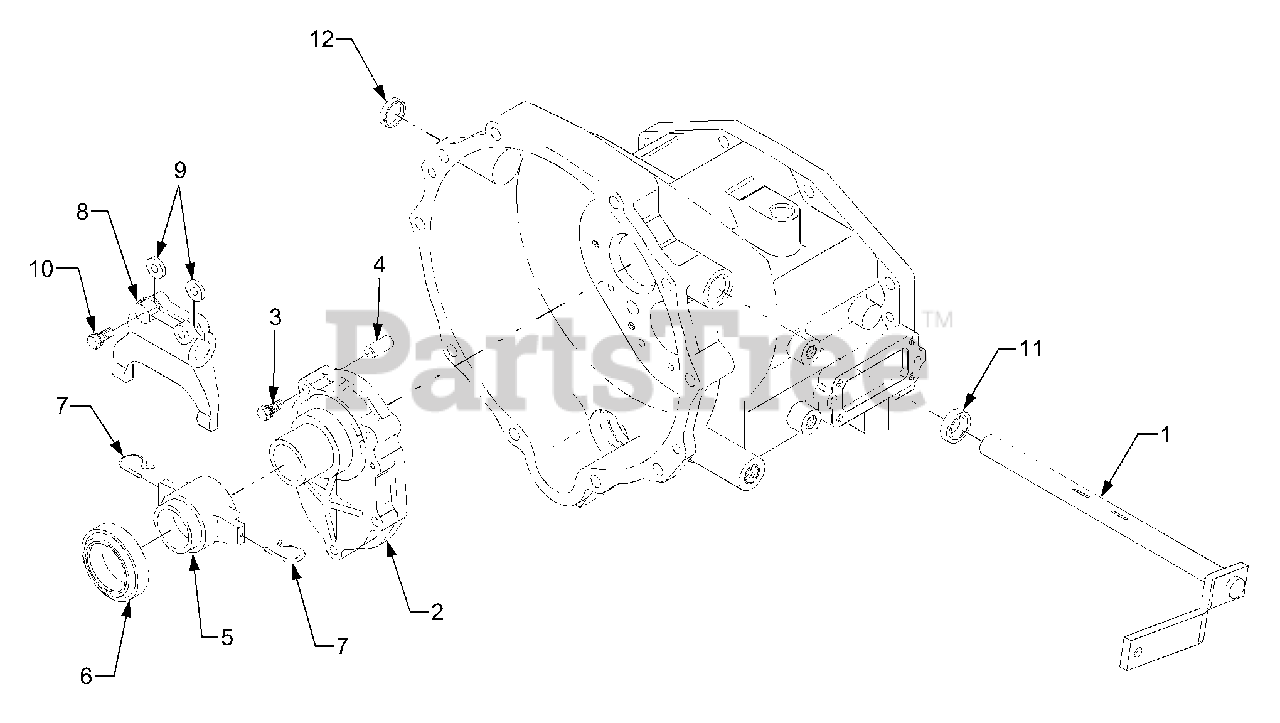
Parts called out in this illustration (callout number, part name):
1	Lever, Main Clutch
2	Case, Propeller Shaft
4	Pin, Straight
5	Hub, Clutch Release
6	Bearing, Release
8	Fork, Clutch Release
